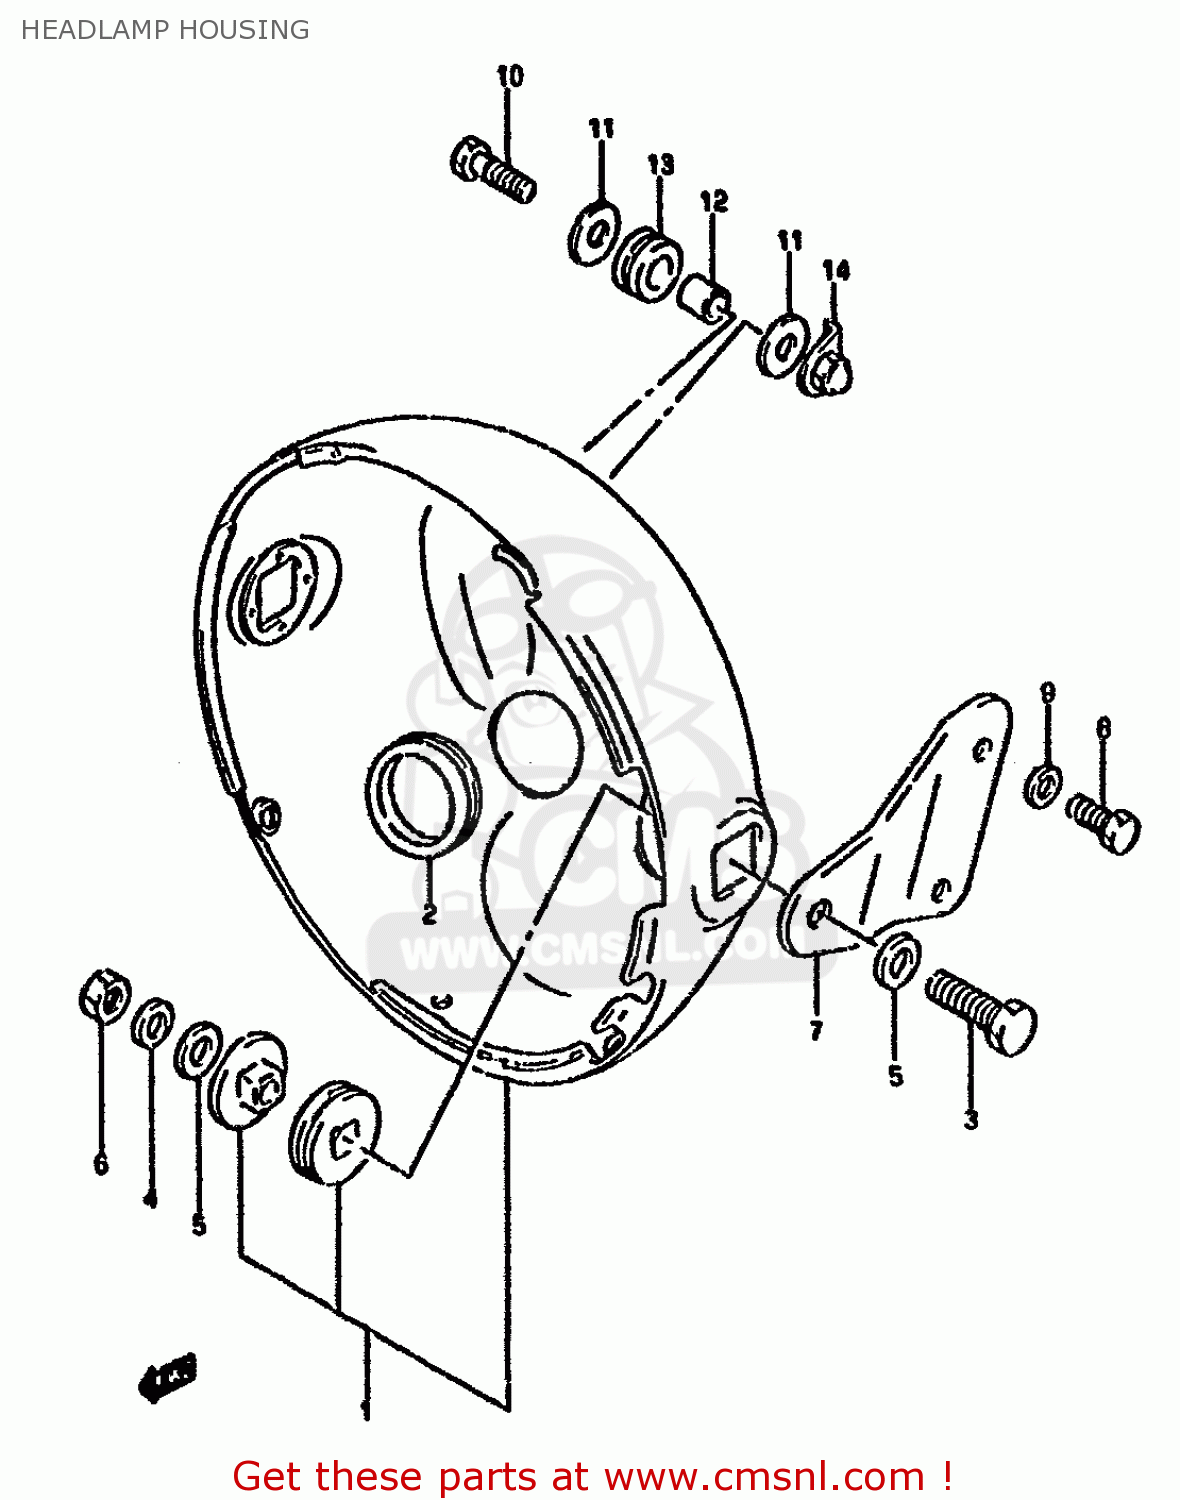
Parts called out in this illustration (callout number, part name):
1	HOUSING,HEADLAMP
2	GROMMET
3	BOLT
4	WASHER,LOCK
5	WASHER
6	NUT
7	STAY,HEADLAMP HOUSING,R
8	BOLT
9	WASHER
10	BOLT
11	WASHER
12	SPACER(6.5X10.5X12)
13	CUSHION
14	PLATE,HEADLAMP
